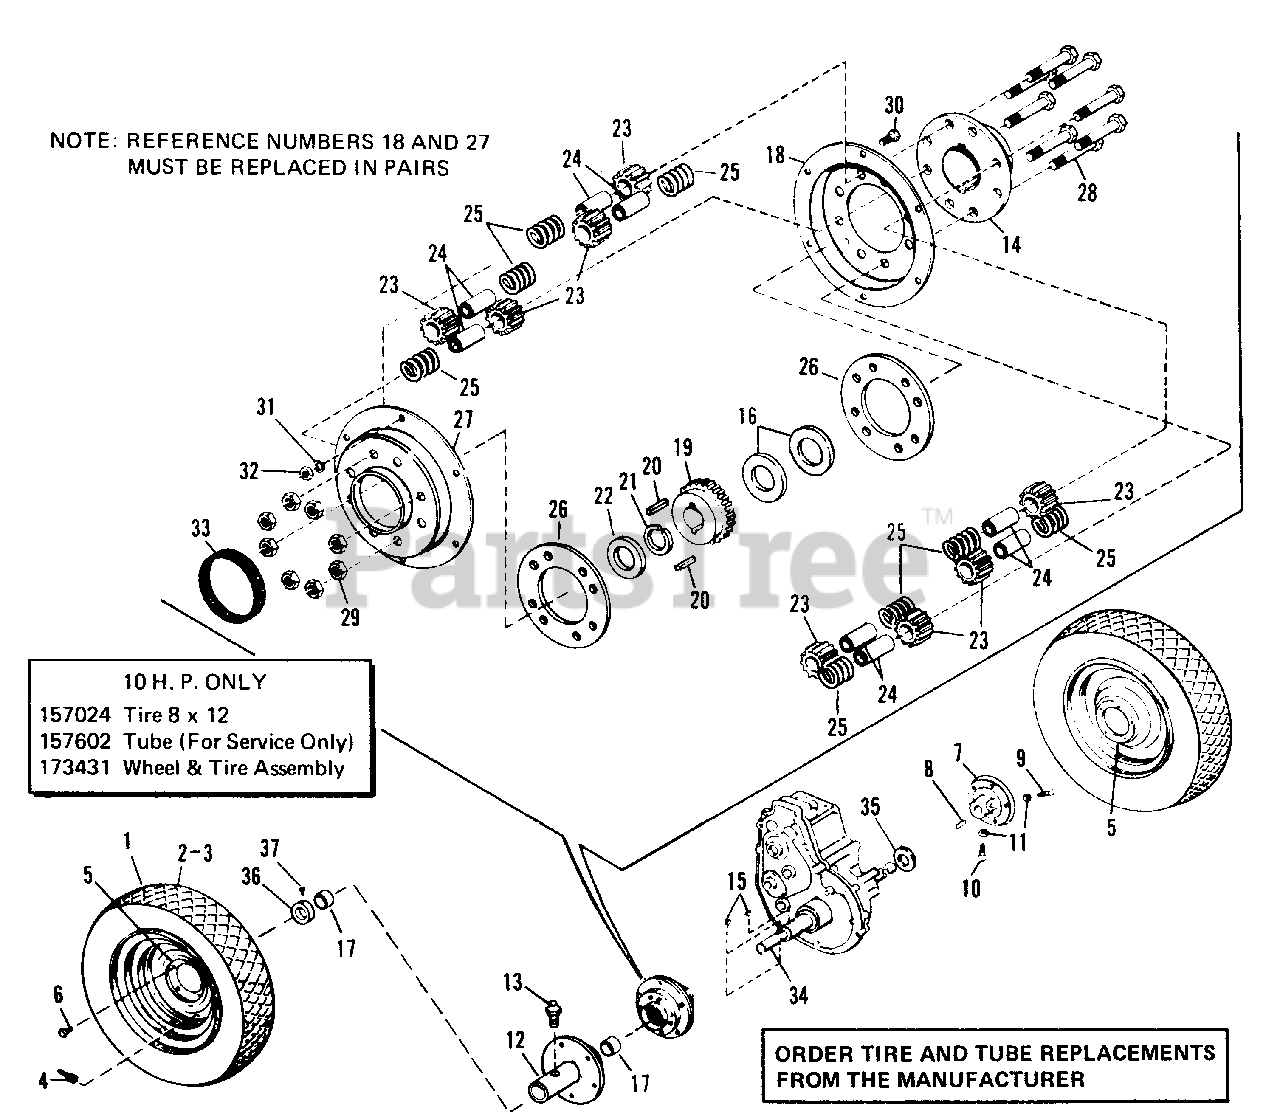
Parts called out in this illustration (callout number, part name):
1	Wheel & Tire Assy.
2	Tire 10-1/2" x 12
4	Valve Stem
5	Wheel Drive
7	Left Hand Wheel Hub
9	Set Screw, 3/8"-16 x 1-1/2"
10	Set Screw, 3/8"-16 x 1"
11	Hex Jam Nut, 3/8"-16
12	R.H. Wheel Hub Assy.
13	Grease Fitting
14	Differential Carrier
16	Axle Washer
18	Differential Cover
19	Differential Gear
20	Hi-Pro Key
21	Retaining Ring
22	Axle Washer
23	Differential Pinion
24	Differential Pinion Spindle
26	Ring Spacer
27	Differential Cover
28	Hex Capscrew, 3/8"-16 x 2-1/2"
29	Full Lock Hex, Nut, 3/8"-16
30	Hex Capscrew, 1/4"-20 x 5/8"
31	Lockwasher, 1/4"
32	Full Hex Nut, 1/4"-20
33	Differential Cover Seal
34	Rear Axle
36	Axle Collar
37	Set Screw, 5/16"-18 x 3/8"
